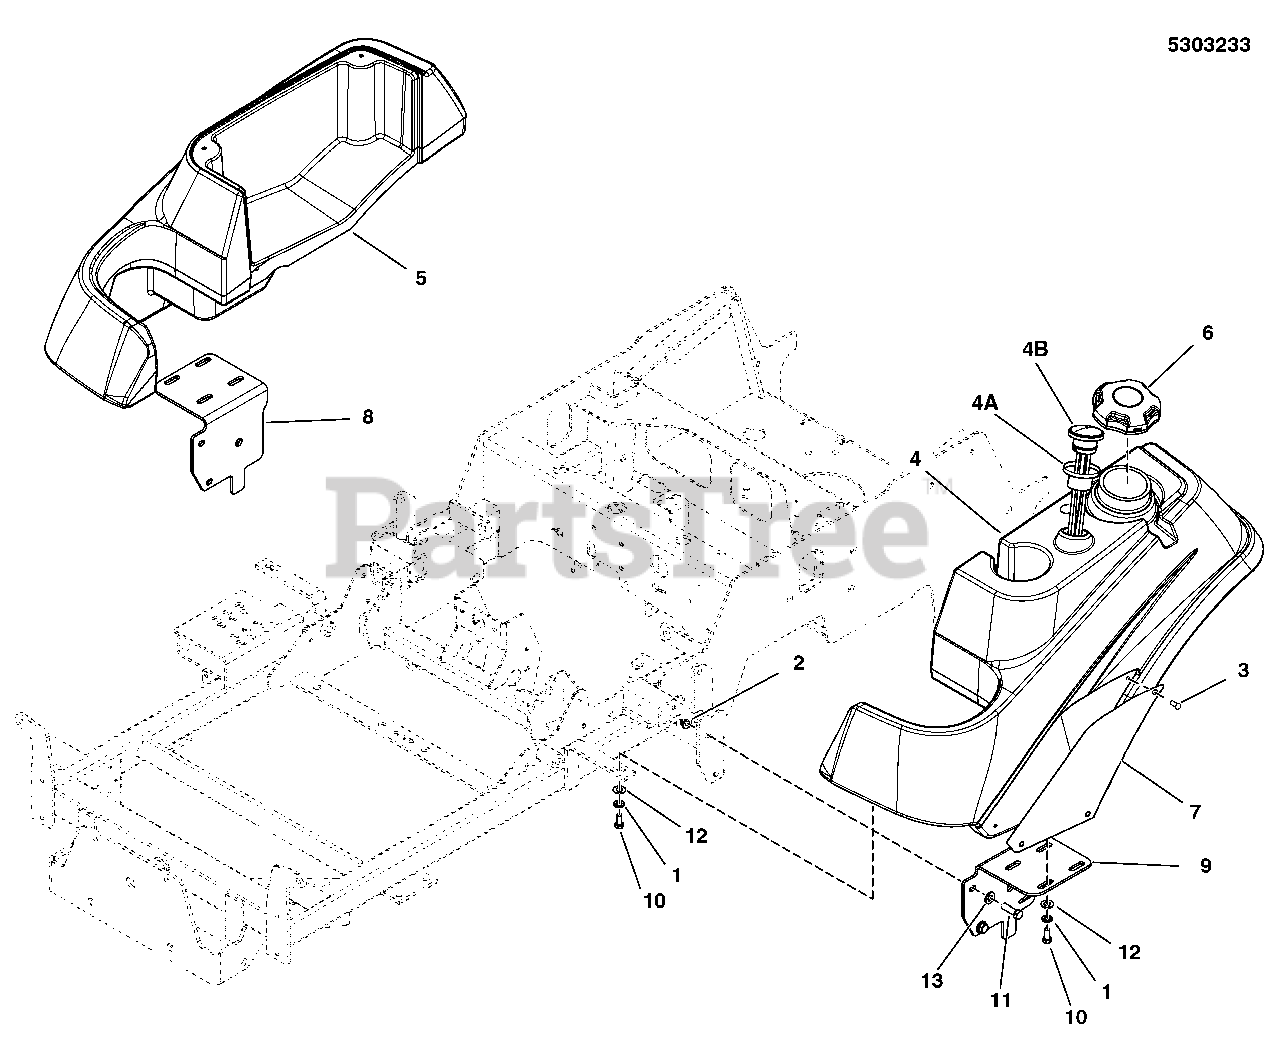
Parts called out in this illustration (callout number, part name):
1	WASHER, 5/16 LOCK YZ
2	NUT, 3/8-16 HEX NYLOCK FLANGE
3	SCREW, #10-24 X 3/8 ALLEN BHBZ
4	TANK, FUEL, IS500 & IS1500 - LH
4A	GROMMET, FUEL GAUGE
4B	GAUGE, FUEL
5	TANK, FENDER, 1500Z - RH
6	FUEL CAP, 3-1/2", MANAGED VENT OUT, 12"
7	BADGE, IS1500Z, ORG
8	WELD, TANK MOUNT, RH - BLK
9	WELD, TANK MOUNT, LH - BLK
10	BOLT, 5/16-18 X 3/4 GD5
11	BOLT, 3/8-16 X 1-1/4 GD5
12	WASHER, 5/16 F436 FLAT
13	WASHER, 3/8 GD.9 FLAT
